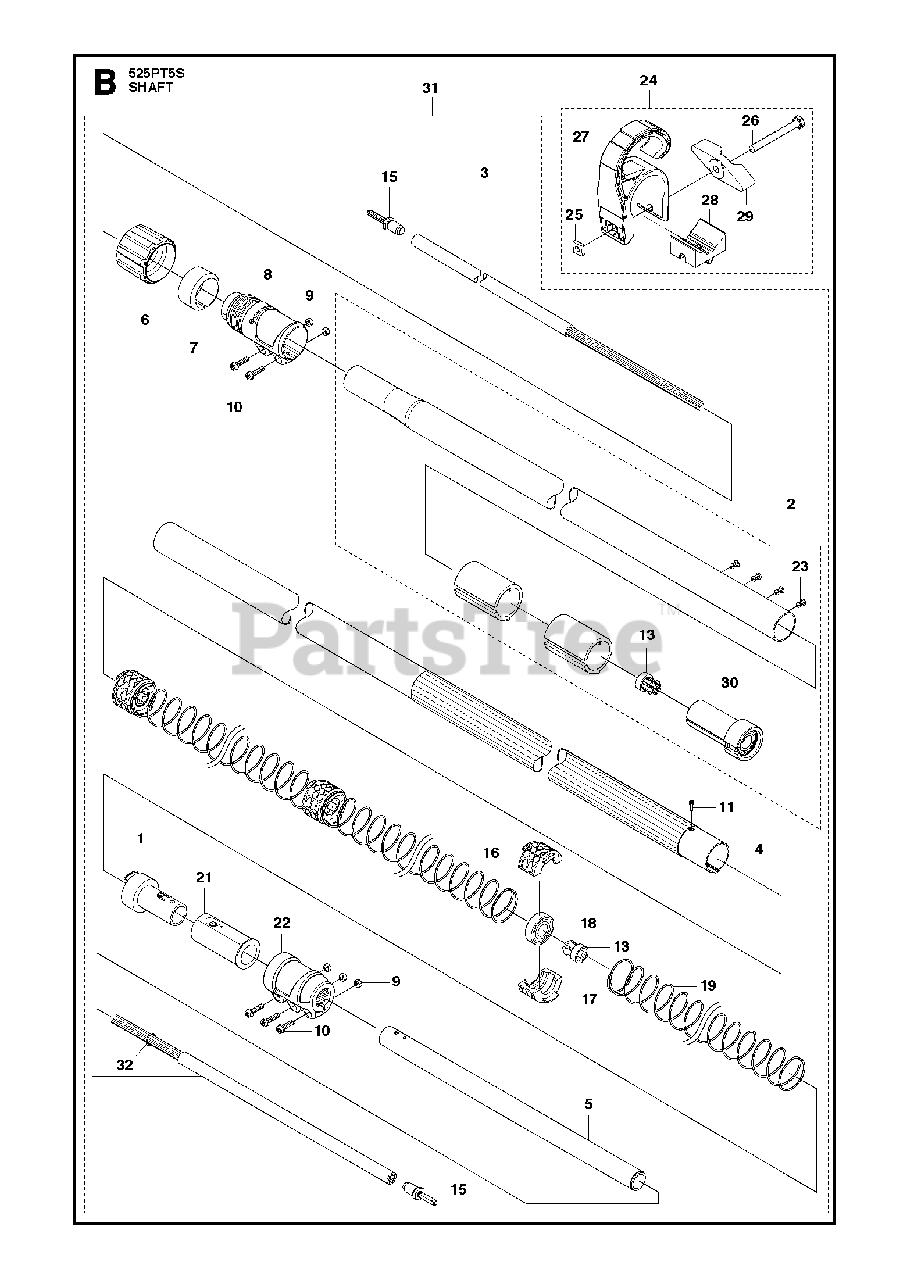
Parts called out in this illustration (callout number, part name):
1	BEARING SLEEVE
2	TUBE UPPER ASSY 525
3	DRIVE SHAFT ASSY
4	FRAME TUBE
5	TUBE
6	NUT
7	RING
8	CLAMPING SLEEVE
9	NUT
10	SCREW
11	SCREW
13	SLIDING SHOE
15	ADAPTER
16	BEARING HOUSING
17	BEARING HOUSING
18	BALL BEARING
19	SPRING
21	SLEEVE
22	CLAMPING SLEEVE
23	RIVET
24	LOOP
25	NUT
26	SCREW M6X55
27	LOOP
28	SPACING BLOCK
29	HANDLE
30	BEARING SLEEVE
31	TUBE DRVESHAFT ASSY TELESCOPIC
32	SNAP RING
